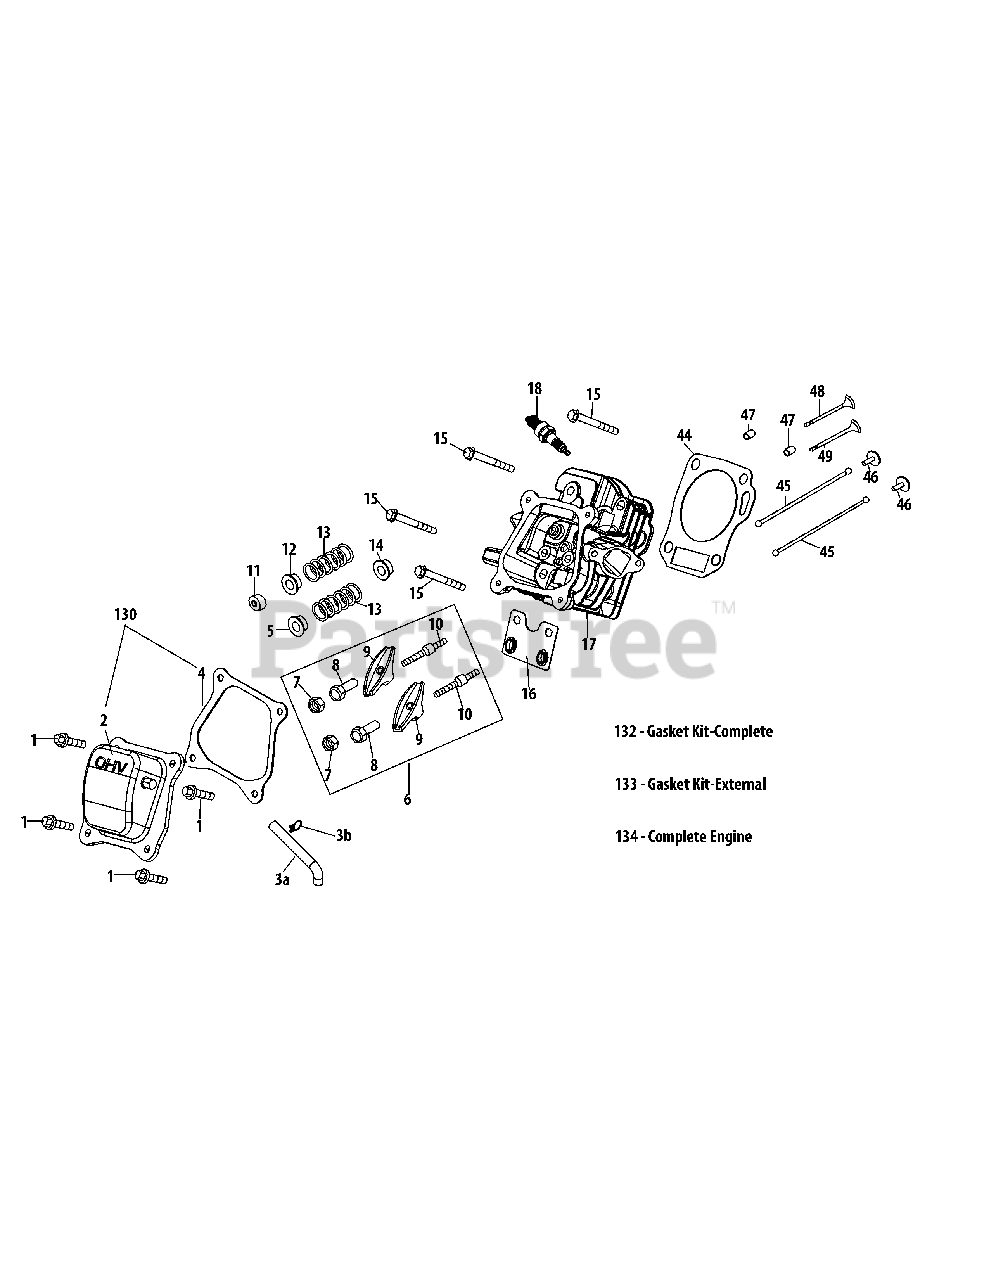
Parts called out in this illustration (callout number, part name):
1	Bolt M6×16
2	Valve Cover
4	Valve Cover Gasket
5	Valve Spring Retainer (Intake)
6	Rocker Arm Assembly
7	Nut, Pivot Locking
8	Adjusting Nut ,Valve
9	Rocker Arm
10	Bolt, Pivot
11	Exhaust Lash Cap
12	Valve Spring Retainer (Exhaust)
13	Valve Spring
14	Valve Seal (Intake)
15	Bolt M8×55
16	Push Rod Guide
17	Cylinder Head Asm
18	Spark Plug/F6Rtc
44	Gasket, Cylinder Head
45	Kit-Push Rod
47	Dowel Pin 10×16
130	Valve Cover Kit
132	Gasket Kit-Complete
133	Gasket Kit-External
134	Complete Engine
